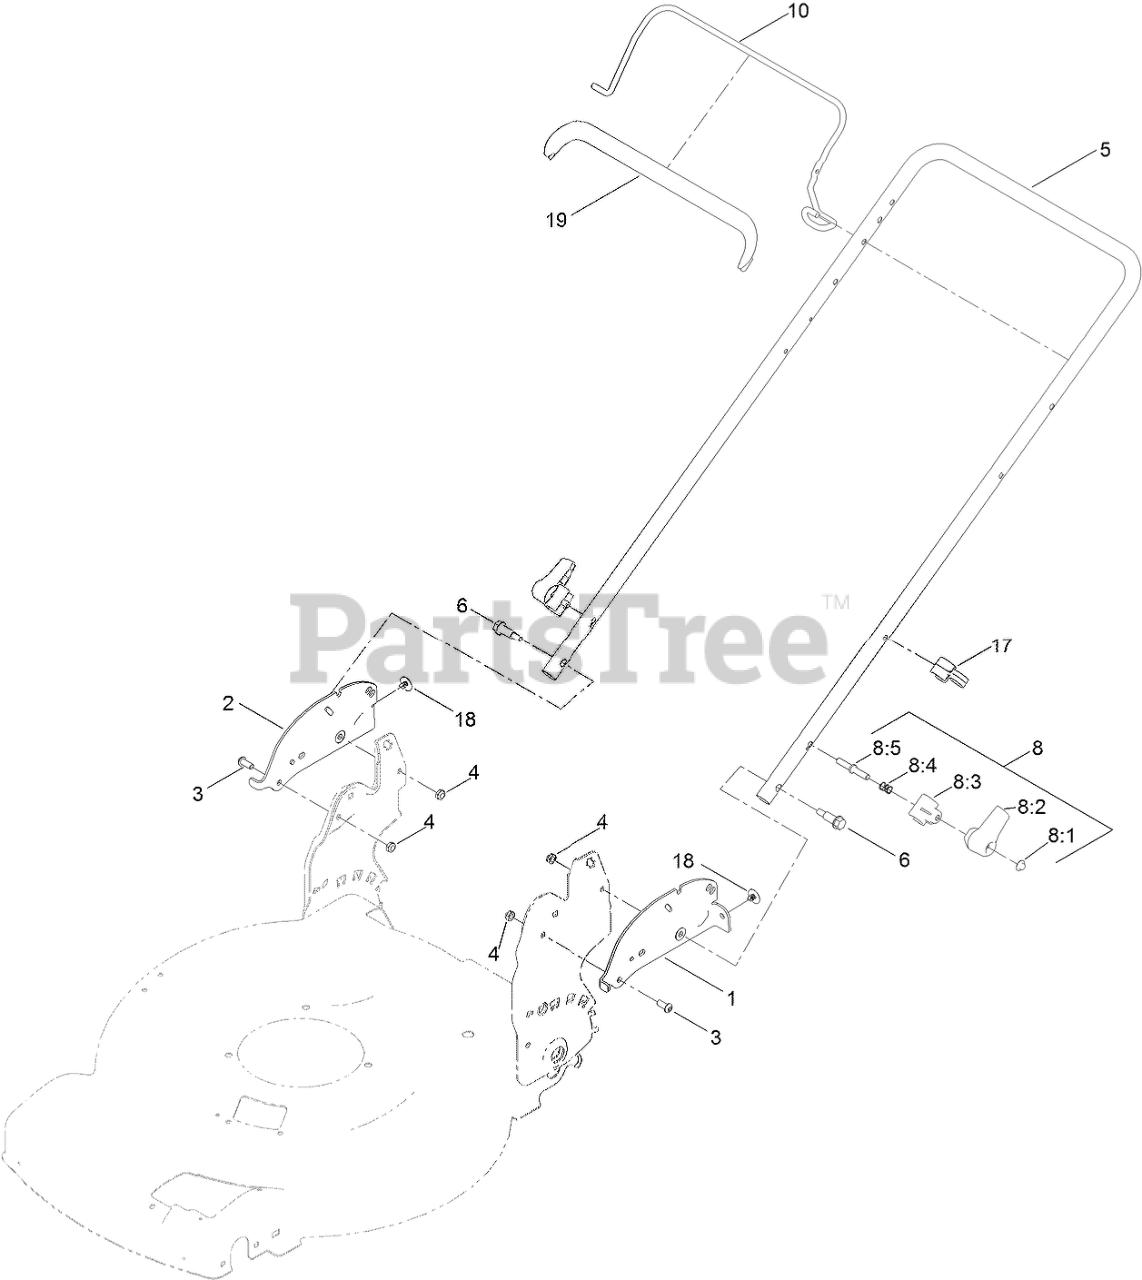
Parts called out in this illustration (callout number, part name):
1	PLATE-HANDLE, LH
2	PLATE-HANDLE, RH
3	SCREW-HSBH
4	NUT-LOCK, NI
6	BOLT-SHOULDER
8	QUICK RELEASE ASM
8:1	NUT-PUSH
8:2	LEVER-RELEASE
8:3	ANCHOR-SPRING
8:4	SPRING-COMPRESSION
8:5	ROD-RELEASE
10	BAIL-BRAKE
17	GUIDE-CABLE
18	CLIP-TREE
19	COVER-BAIL
